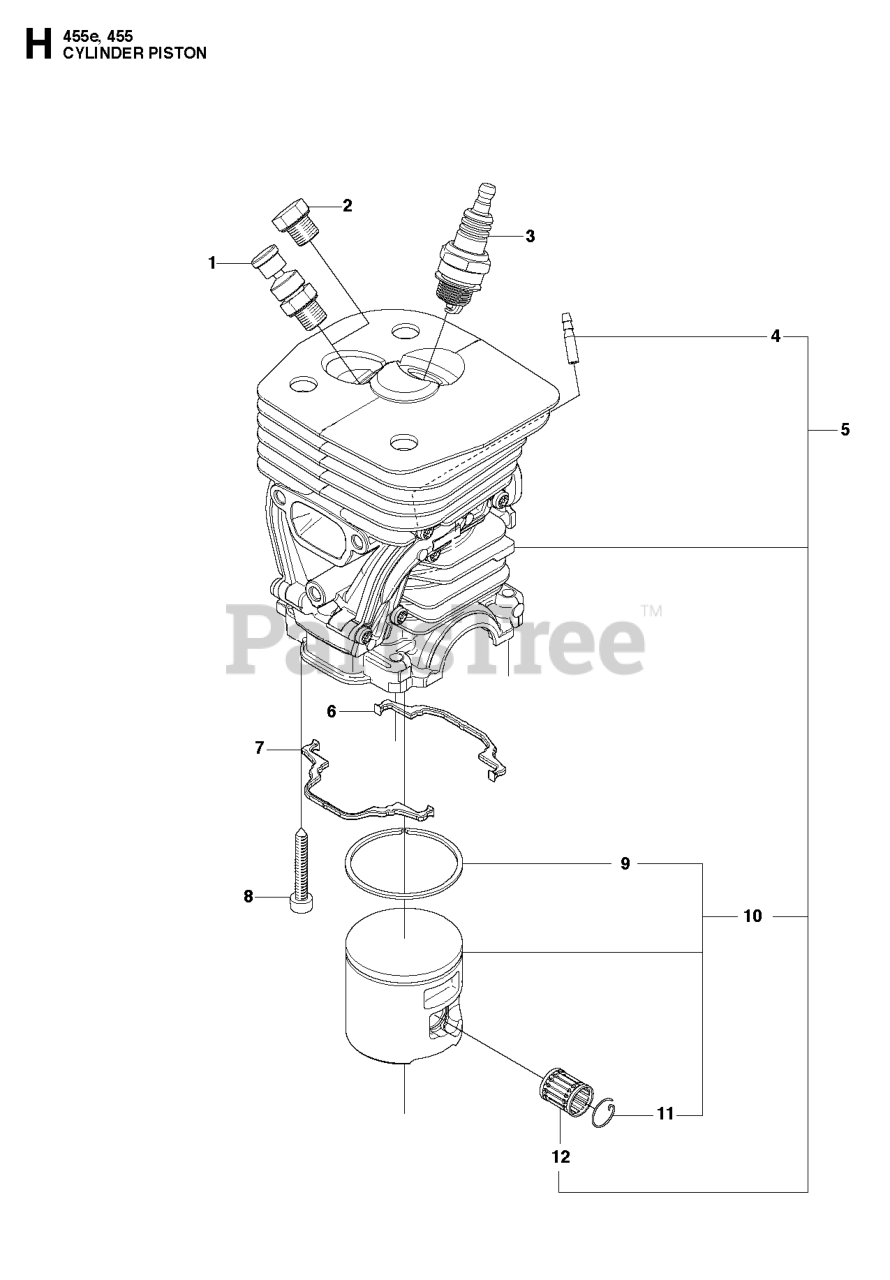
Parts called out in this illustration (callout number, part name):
2	CYLINDER PLUG
3	HQT-1 HH SPARK PLUG - BPMR7A
5	CYLINDER
9	PISTON RING
10	PISTON ASSY
11	WRIST PIN CLIP
12	SUPPORT BUSHING
